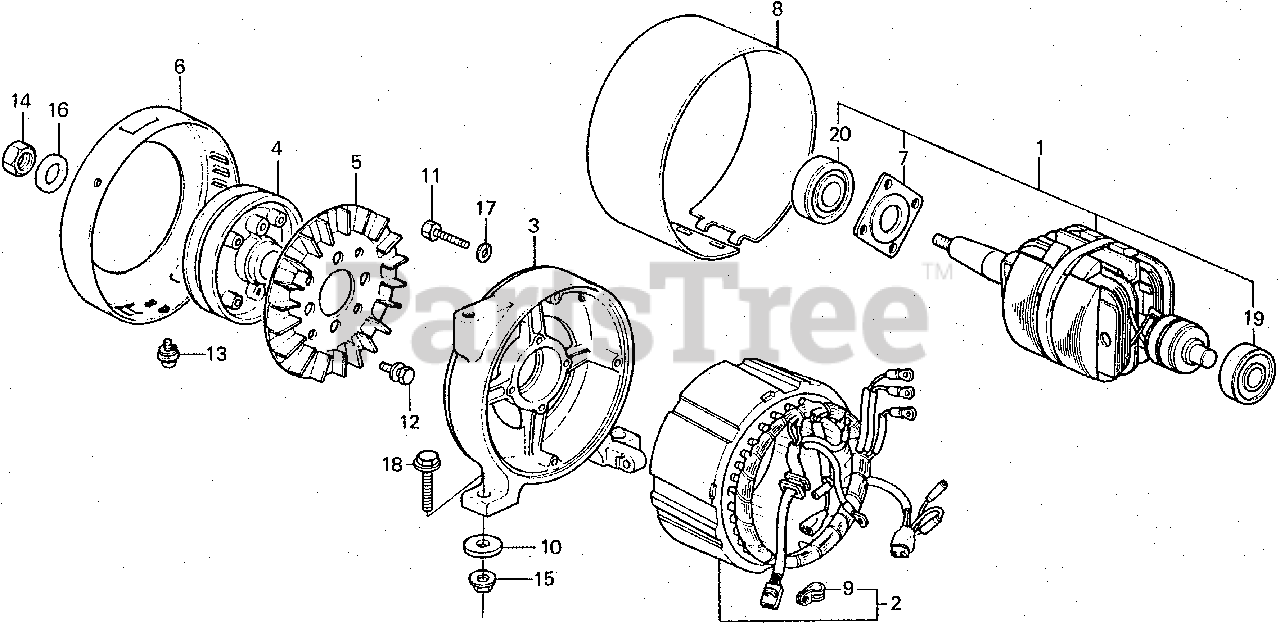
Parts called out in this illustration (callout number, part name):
2	STATOR (NOT AVAILABLE)
3	HOUSING, FR. *NH31* (MCKINLEY WHITE)
4	PULLEY, ALTERNATOR (135MM) *NH1* (BLACK)
6	COVER, FAN *NH31* (MCKINLEY WHITE)
7	PLATE, BEARING SETTING
8	COVER, STATOR *NH31* (MCKINLEY WHITE)
9	CLIP, WIRE
10	WASHER, EX. MANIFOLD
11	BOLT, HEX. (5X32) (NOT AVAILABLE)
12	BOLT-WASHER (6X12)
13	SCREW-WASHER (5X10)
14	NUT, HEX. (18MM) (NOT AVAILABLE)
15	NUT, FLANGE (10MM)
16	WASHER, FLAT (18MM) (NOT AVAILABLE)
17	WASHER, SPRING (5MM)
18	BOLT, FLANGE (10X32)
19	BEARING, RADIAL BALL (6304UU)
20	BEARING, RADIAL BALL (6306UU)
